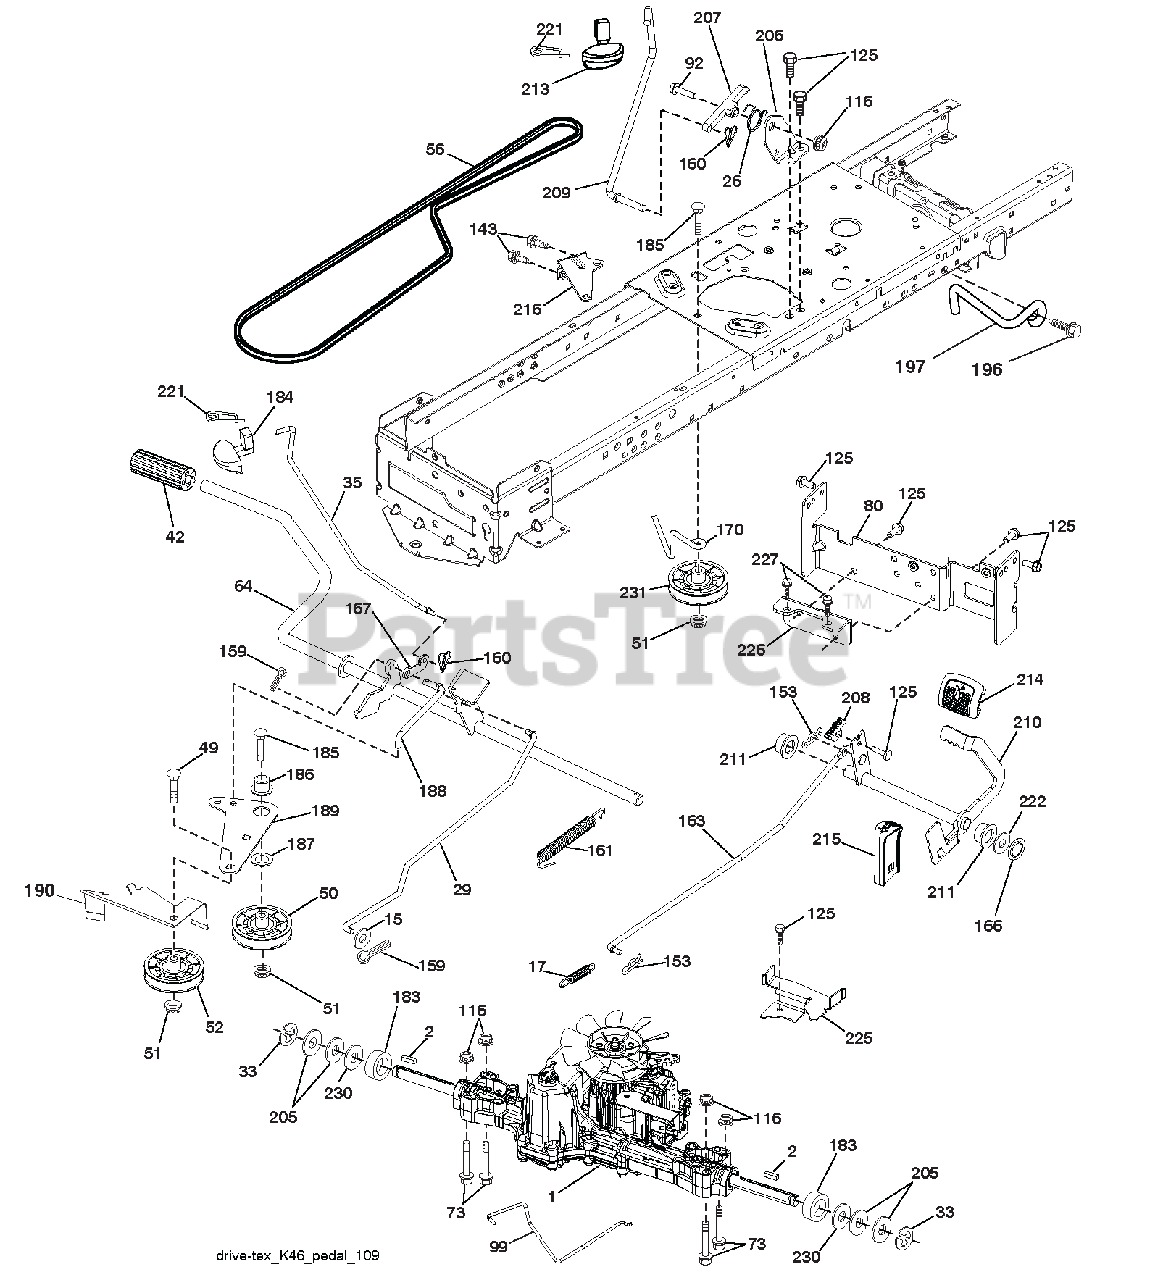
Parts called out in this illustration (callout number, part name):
2	KEY.SQUARE.2.0 X .1845/.1865
15	WASHER.13/32 X 13/16 X 16 GA.
17	SPRING.BRAKE.K46.GREEN
26	SPRING.RETURN.CRUISE
29	ROD.BRAKE.K46
33	E-RING.#5133-75
35	ROD.BRAKE.PARKING.LT.TEX
42	COVER PEDAL BLK ROUND
49	BOLT.RDHD.3/8-16UNCX1-3/4.GR5
50	IDLER.FLAT.910"OFFSET
51	Nut, Hex, Flangelock 3/8-16
52	IDLER.V-GROOVE.910"OFFSET
56	V-BELT.MOWER.92.40.42/K46
64	SHAFT ASM.PEDAL.BRK.CNTRL.PCH
73	BOLT 5/16-18 X 2 1/2 G.5
80	STRAP.TORQUE.K46/18"TEX
92	Bolt, Hex Head 5/16-18 x 1-1/4
99	ROD.SPRING.BYPASS.K46.LT.Z
116	Nut, Lock Hex Flange 5/16-18 u
125	SCREW.5/16-18X3/4.SMGML.TAP/BL
143	SCREW.THDROL.5/16-18 X 1/2TYTT
153	RETAINER SPRING
159	PIN.COTTER.1/8 X 3/4.CAD.
160	RETAINER.CLIP(M).DIA.290
161	SPRING.RETURN.CLUTCH.6.75
163	ROD CONTROL
166	NUT PUSH .625
167	LATCH.BRAKE.PARKING
170	KEEPER.CENTER SPAN.1.688
183	SPACER.AXLE.HYDRO/PEERLES
184	HANDLE.PARKNG.BRAKE.LT.TEX.667
185	BOLT.RDHD.3/8-16UNC X2-3/4 GR5
186	SPACER.RETAINER
187	WASHER.13/32 X 2 X 10 GA.
188	LINK.CLUTCH.GROUND DRIVE
189	BELLCRANK.GROUNDRIVE.NSTG/NSTL
190	KEEPER.BELLCRANK.DRIVE.GROUND
196	SCREW.3/8-16X1.SMGML.TAP/R.BLK
197	LINK CLUTCH ANTI-ROTATION
205	WASHER.25/32 X 1-5/8 X 16GA.
206	BRACKET.MOUNT.LATCH.CRUISE
207	LATCH.CONTROL.CRUISE
208	GEAR SECTOR.CONTROL.CRUISE
209	ROD.CONTROL.CRUISE
210	ROCKER ASM.PEDAL CONTROL.TEXLT
211	BEARING.NYLON.BLK..629 ID.
213	KNOB.CONTROL.CRUISE
214	PAD PEDAL FORWARD
215	PEDAL REVERSE
216	BRACKET.PULLEY.IDLER.WTEX
221	RETAINER.SPRING.CLIP.HANDLE
222	WASHER.21/32X1-1/4.10GA.N/PLTD
225	KEEPER.BELT.TRANSAXLE.K46
226	BRACKET.MOUNT.TORQUE.K46.TLT
227	SCREW 5/16-18 X 3/4
230	WASHER.HARDEN..793 X 1.637X060
231	IDLER.V-GROOVE.1.688"OFFSET
